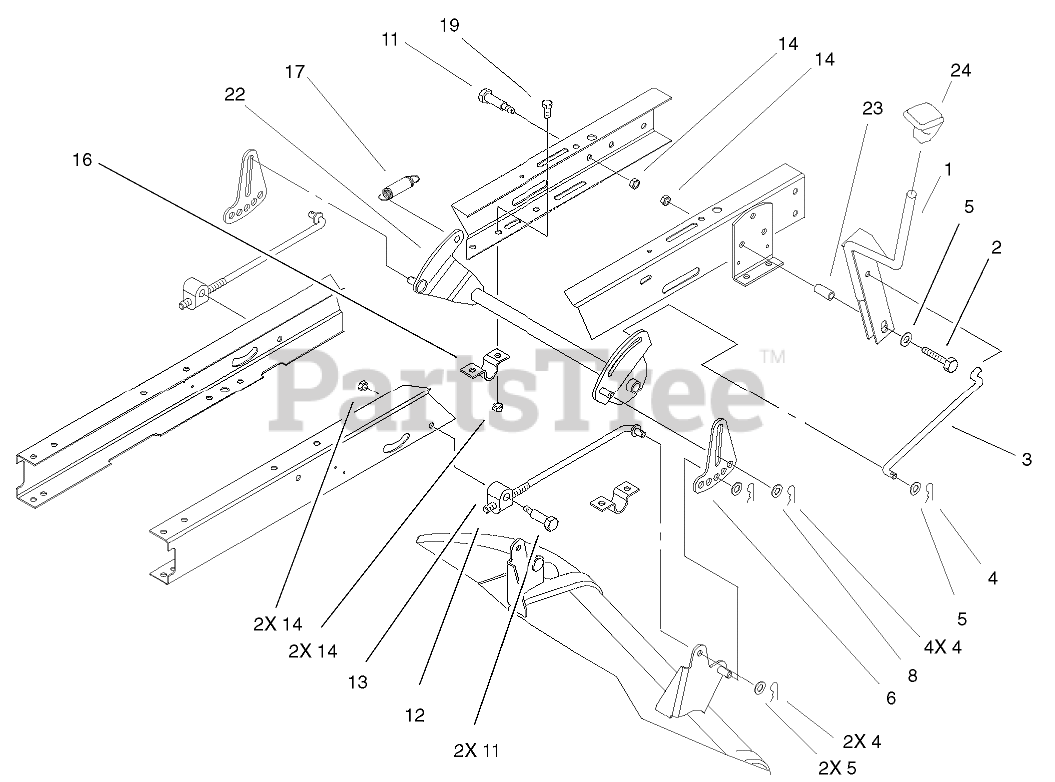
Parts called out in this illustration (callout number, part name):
1	HOC LEVER ASM
2	SCREW-HH
3	LINK-HOC
4	PIN-COTTER
5	WASHER-FLAT
6	LINK-ADJUSTING, HOC
8	WASHER-HARDENED
11	SCREW-SHOULDER, HH
12	ROD-HANGER, REAR
13	TRUNNION-HOC
14	NUT-LOCK, NI
16	CLAMP-PIVOT, HOC
17	SPRING-EXTENSION
19	SCREW-HH
22	PIVOT ASM
23	SPACER
24	KNOB-SHIFT
